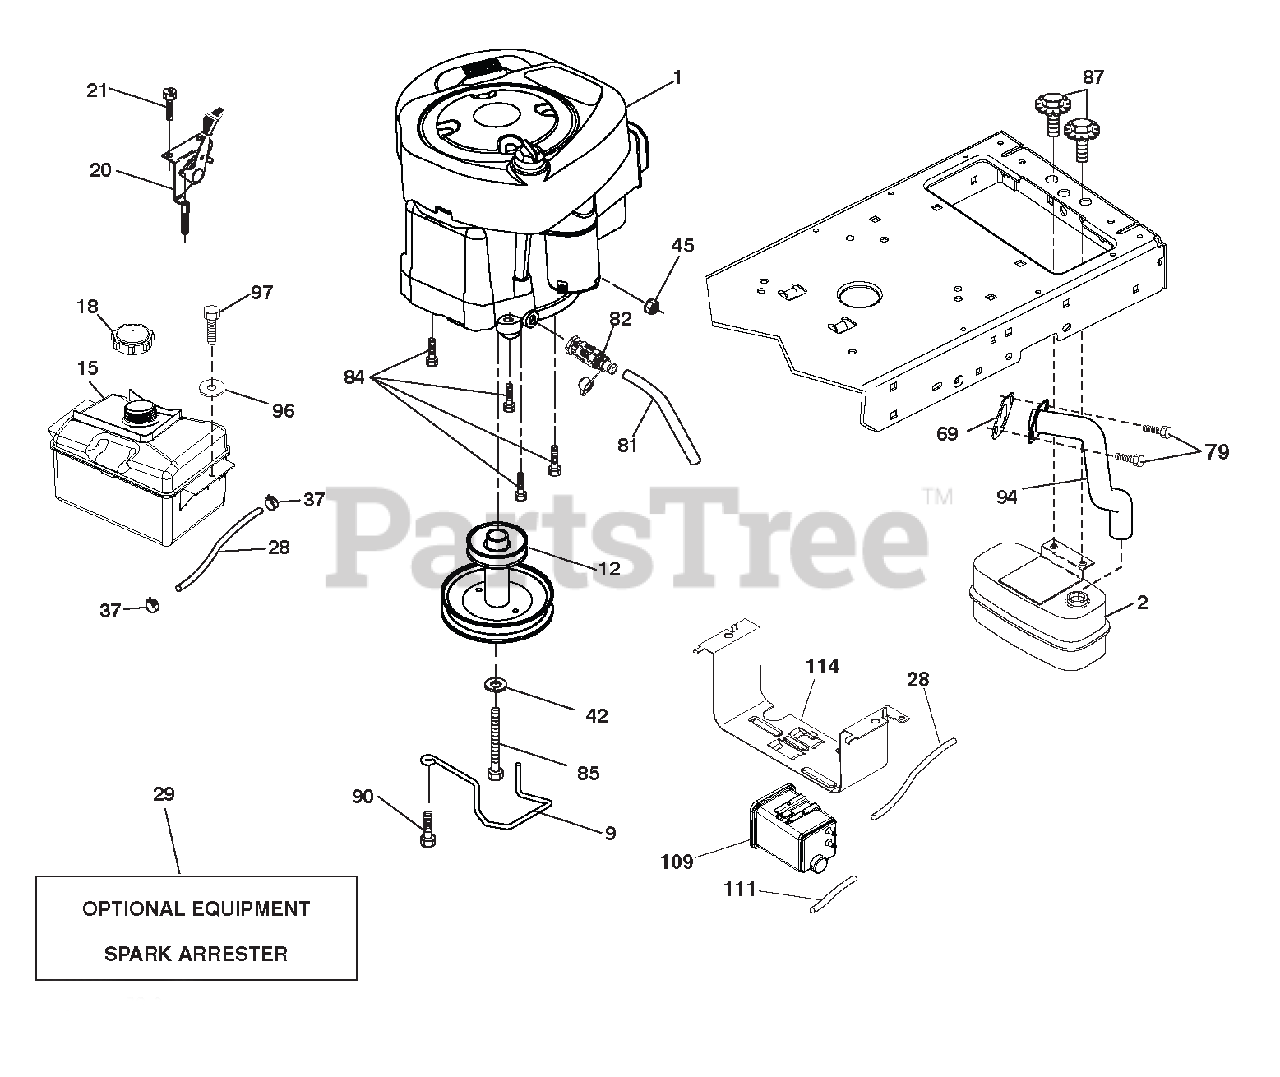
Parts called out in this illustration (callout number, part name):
1	ENGINE BRIGGS MODEL NO. 331777-4372-G1(440263) (ORDER PARTS FROM ENGINE MANUFACTURER.)
2	MUFFLER.SINGLE.CYL.KOHL.COURAG
9	KEEPER.BELT.ENGINE.4.25"NSTG
12	PULLEY ENGINE
15	TANK.FUEL.FRT.1.5 GAL
18	CAP FUEL
20	CONTROL THROTTLE/CHOKE
28	LINE.FUEL.22"FRONT.EMIS.CA.LP
29	KIT.SPARK ARRESTOR(392390 B&S)
37	CLAMP.HOSE.BLK.
42	WASHER.LOCK.HVY HLCL.SPR.7/16
45	Nut, Keps Hex 1/4-20 unc
69	Gasket Eng 1 313 Id Tin Plated
79	SCREW.SOCKET HD.5/16-18 X .75
81	TUBE.DRAIN.OIL.EASY
82	VALVE OIL DRAIN
84	Screw 3/8-16 x <
85	BOLT.HEX.7/16-20X4XGR5-1.5THR.
87	BOLT.5/16-18UNCX3/4 W/SEMS.BLK
90	SCREW.3/8-16X1.SMGML.TAP/R.BLK
94	EXHAUST TUBE
96	WASHER.9/32 X 7/8 X 16GA.
97	SCREW.HEXWSH.THDROL.1/4-20X3/4
109	CANISTER.CARBON.FILTER ASM.TEX
111	PURGE.LINE.CARB
114	CRADLE.CANISTER.CARBON
